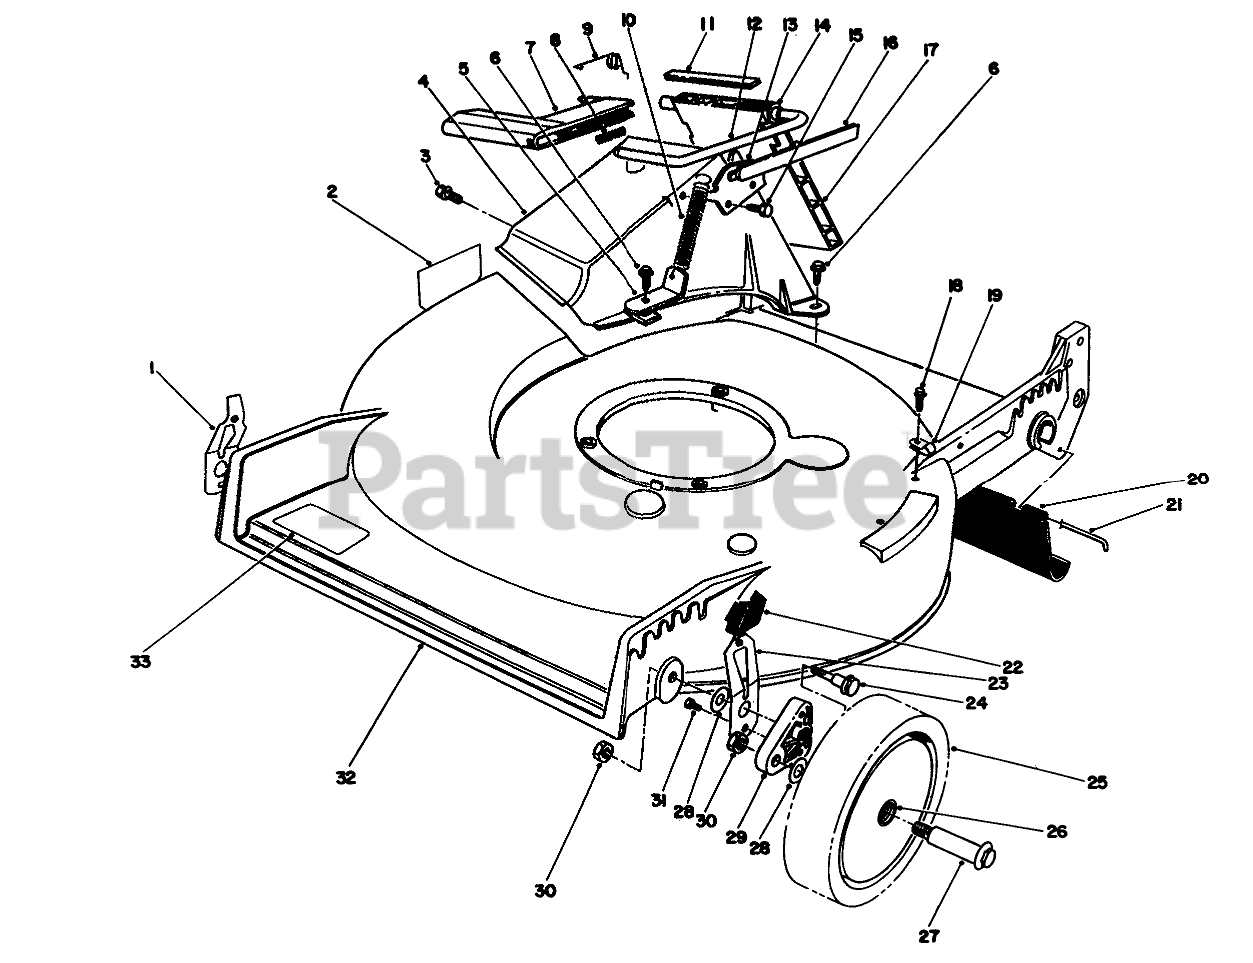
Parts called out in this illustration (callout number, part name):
1	RH SPRING ARM ASSEMBLY
2	DECAL-DANGER
3	SCREW AND WASHER ASM
4	DISCHARGE TUNNEL
5	Bracket-Spring
6	SCREW-HWH
7	Handle-Door
8	Spring
9	RETAINER-DOOR
10	SPRING-DOOR
11	Cover-Door
12	Rod-Door
13	DOOR LATCH PLATE
14	BUSHING-NYLON
15	SCREW-PLASTITE
16	Cover-Handle
17	Door-Discharge
18	SCREW-HWHTF
19	CLAMP-R
20	SHIELD-TRAILING
21	ROD-SHIELD
22	KNOB-ARM
23	LH SPRING ARM ASSEMBLY
24	SCREW-SHOULDER
25	Wheel & Tire Assembly (Incl. Ref. #26)
26	BUSHING
27	WHEEL BOLT
28	WASHER
29	ARM-PIVOT, FRONT
30	Nut
31	SCREW-HWH
32	Housing Assembly (Incl. Ref. #2 & 6)
33	DECAL
